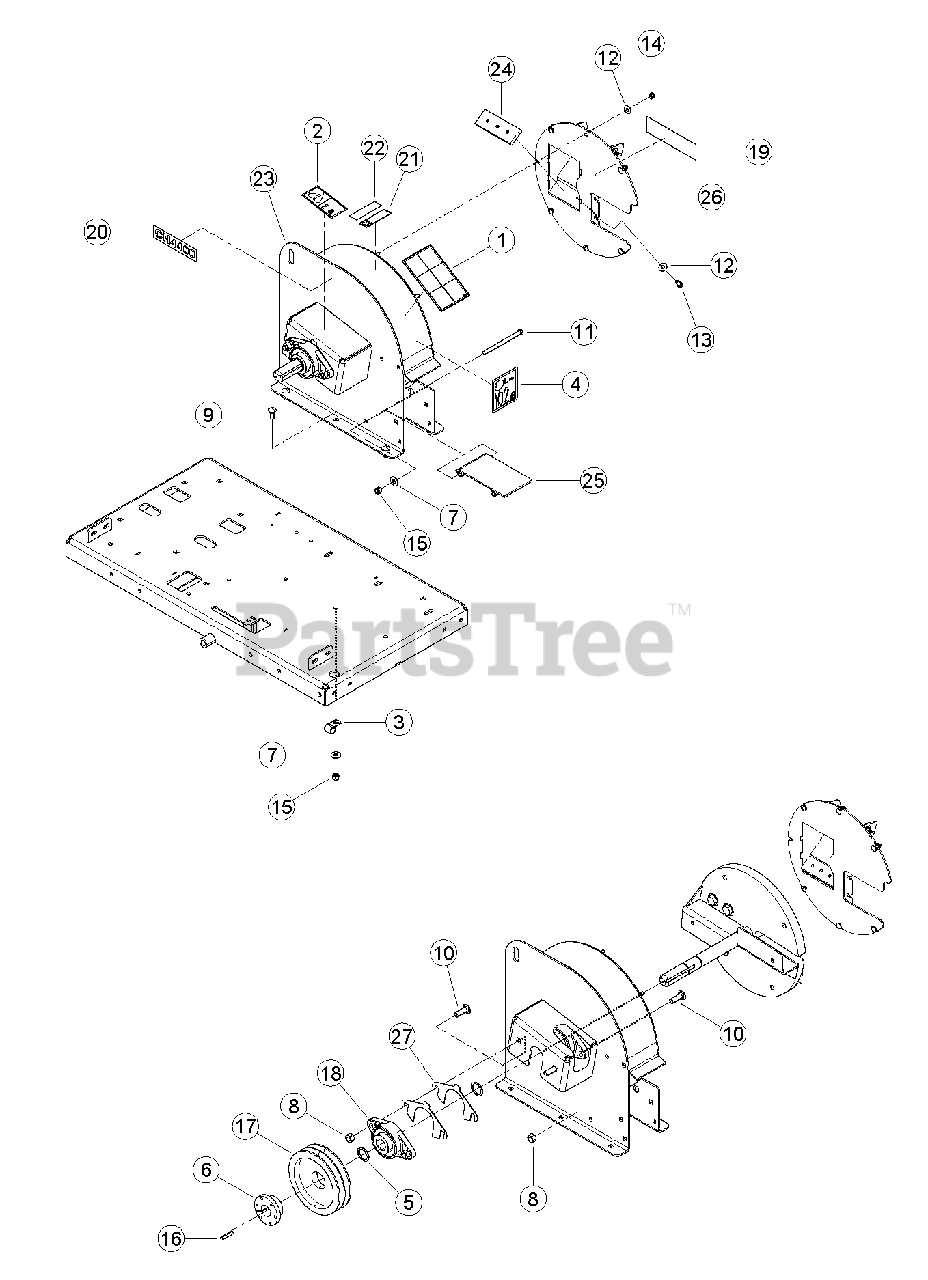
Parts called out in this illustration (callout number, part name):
1	DECAL, OPERATING INSTRUCTIONS ISO
2	DECAL, MAINTENANCE ISO
3	CLAMP, 9/16" COATED
4	DECAL, 107 DB (CE COMPLIANT ONLY)
5	SNAP RING, 1-1/4 EXT. HEAVY DUTY
6	BUSHING, SDS 1-1/4"
7	WASHER, 3/8 FLAT ZP
8	NUT, 1/2 CENTERLOCK GRB ZP
9	BOLT, 3/8 X 1 CRG GR5 NC ZP
10	BOLT, 1/2 X 1-1/2 CRG GR5 ZP
11	BOLT, 3/8 X 5 HEX HD GR5 ZP
12	WASHER, 5/16 FLAT ZP
13	BOLT, 5/16 X 5/8 HEX HD GR5 ZP
14	NUT, 5/16 NE NYLOCK ZP
15	NUT, 3/8 NE NYLOCK ZP
16	KEY, 1/4 SQUARE X 1-1/2 LONG PLAIN
17	SHEAVE, 2B 6.6 SDS
18	BEARING, 1-1/4" DIA 2 BOLT FLANGE
19	DECAL, ECHO BEARCAT 6.82 X 1.90
20	DECAL, MODEL CH4400
21	DECAL, INFORMATION (CE COMPLIANT ONLY)
22	DECAL, ATLANTIC BRIDGE LTD INFO (CE COMPLIANT ONLY)
23	WELDMENT, CHIPPER HOUSING
24	ANVIL, CHIPPER
25	WELDMENT, CHIP DEFLECTOR
26	WELDMENT, ROTOR COVER
27	SHIM, BEARING (WAS 75550-00, REMOVED)
